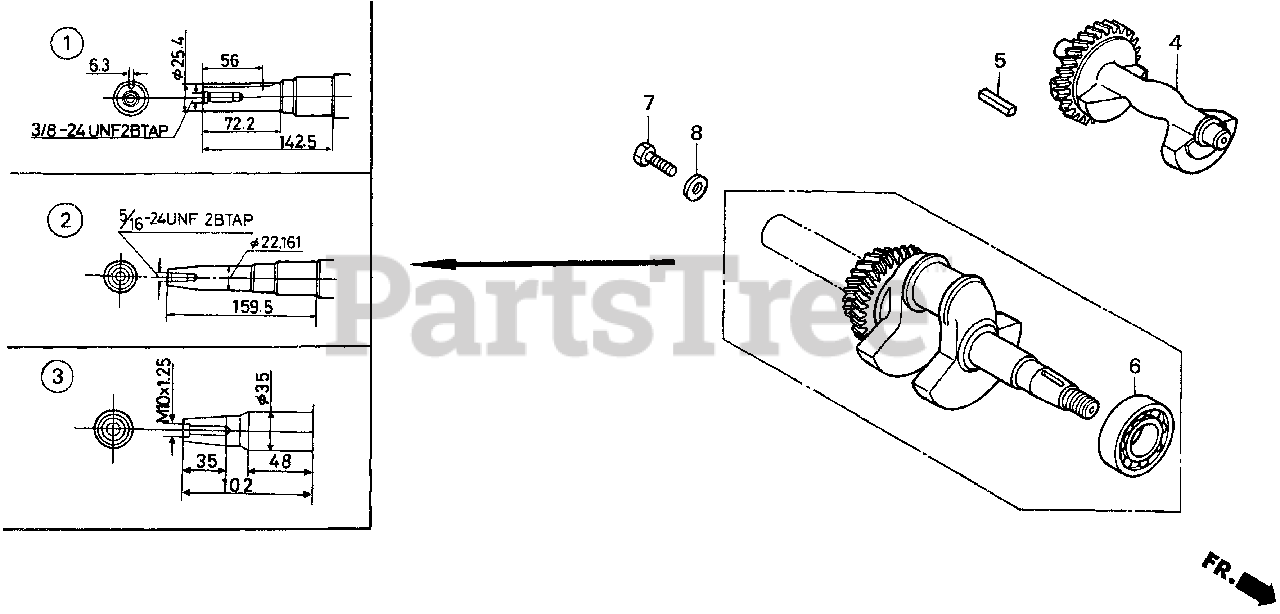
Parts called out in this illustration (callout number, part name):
1	CRANKSHAFT (Q-TYPE)
4	WEIGHT, BALANCER
5	KEY (6.3X6.3X43)
6	BEARING, RADIAL BALL (6207)
